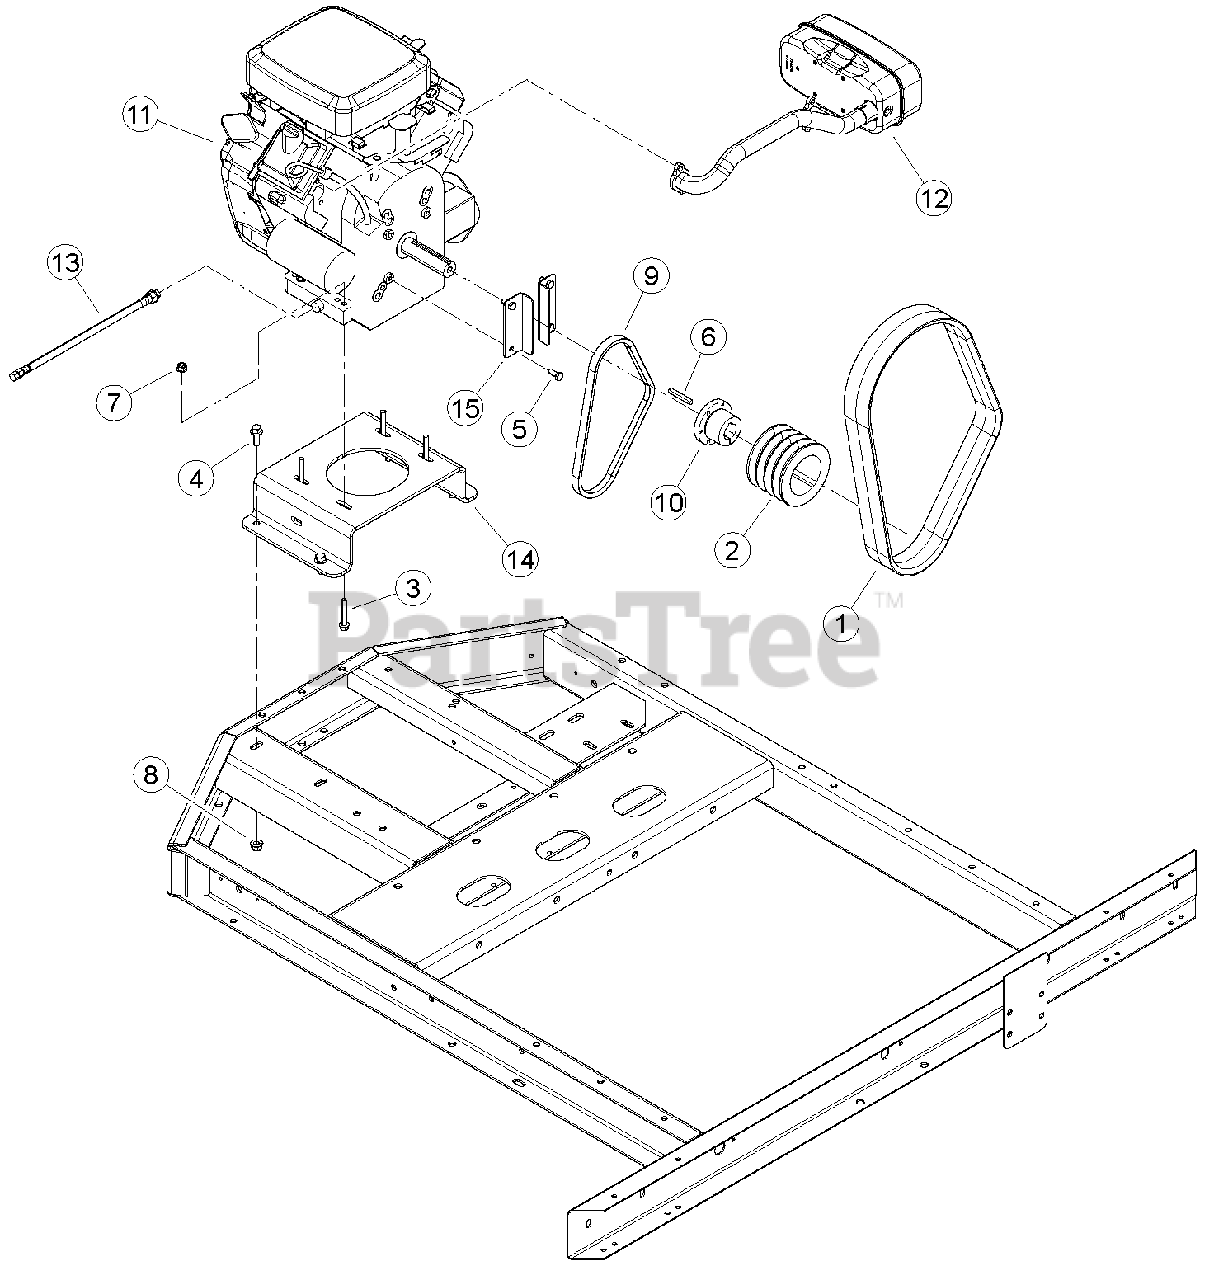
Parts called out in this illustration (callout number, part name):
1	BELT, 3RB48
2	SHEAVE, 4B4.2 SD
3	BOLT, 5/16 X 2 FLANGE NC
4	BOLT, 3/8 X 1 FLANGE NC
5	BOLT, 5/16-24 X 3/4" GR5 HHCS ZP
6	KEY, 1/4" SQ X 2" PLAIN
7	NUT, 5/16-18 NYLOCK FLANGE
8	NUT, 3/8-16 NYLOCK FLANGE
9	BELT, 29" C/S
10	BUSHING, SD 1-1/8"
11	ENGINE, 23 HP BRIGGS (FOR SERVICE SEE ENGINE OWNER'S MANUAL OR NEAREST BRIGGS & STRATTON INDUSTRIAL ENGINE DEALER)
12	MUFFLER, B&S SIDE MOUNT OIL FILTER SIDE (FOR SERVICE SEE ENGINE OWNER'S MANUAL OR NEAREST BRIGGS & STRATTON INDUSTRIAL ENGINE DEALER)
13	HOSE ASSEMBLY, CRANKCASE DRAIN
14	PLATE, ENGINE MOUNT
15	SHIELD, CRANKSHAFT
